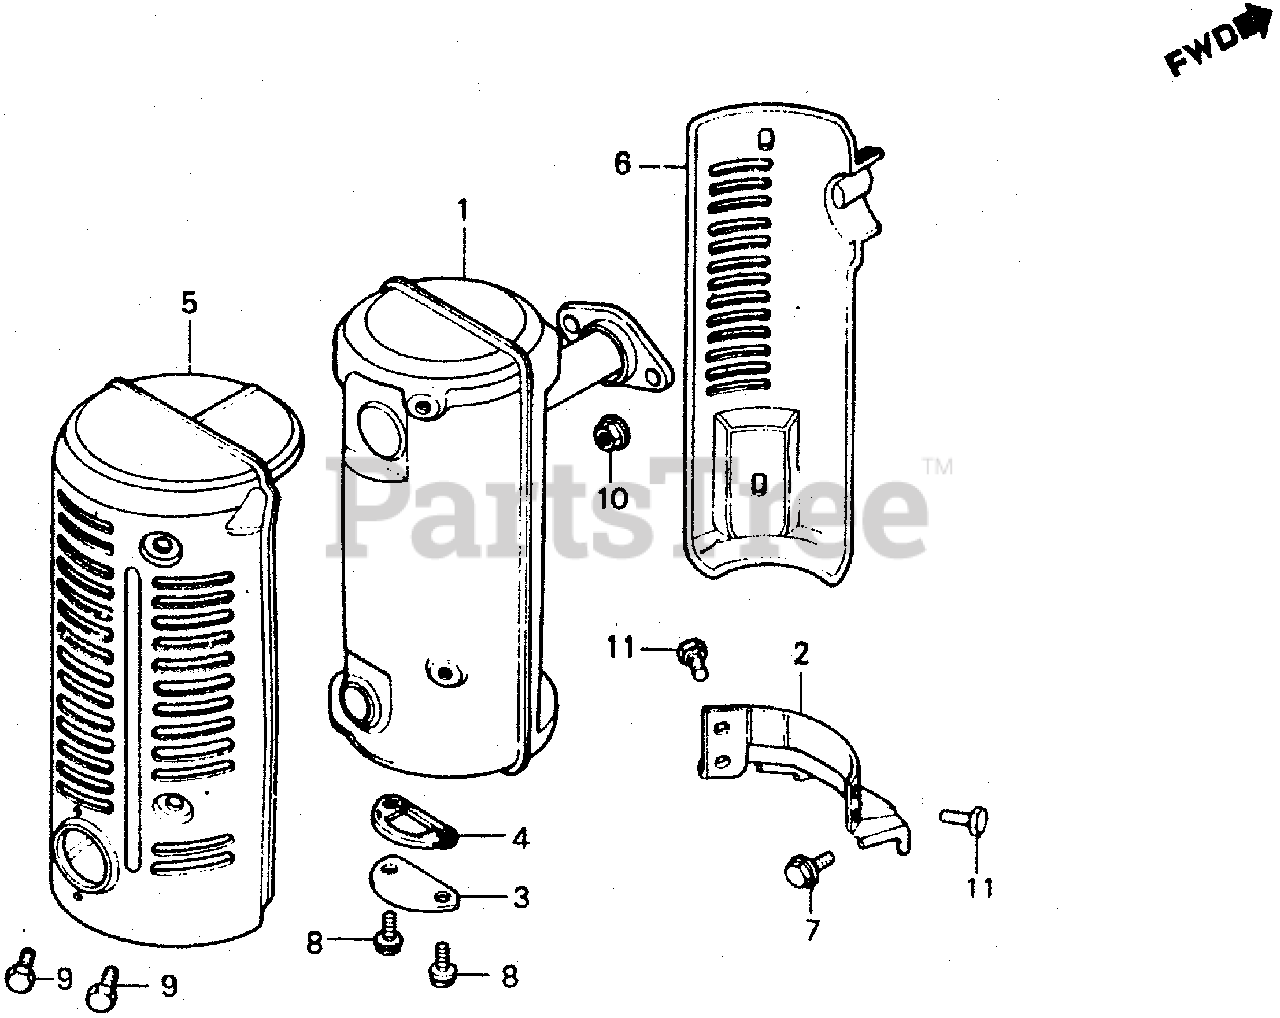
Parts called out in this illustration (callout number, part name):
1	MUFFLER ASSY.
2	STAY, MUFFLER
3	LID, MUFFLER
4	GASKET, MUFFLER LID
5	PROTECTOR A, MUFFLER
6	PROTECTOR B, MUFFLER
7	BOLT, FLANGE (8X16)
8	BOLT, HEX. (6X12)
9	BOLT, HEX. (6X6)
10	NUT, FLANGE (8MM)
11	BOLT, FLANGE (6X10)
